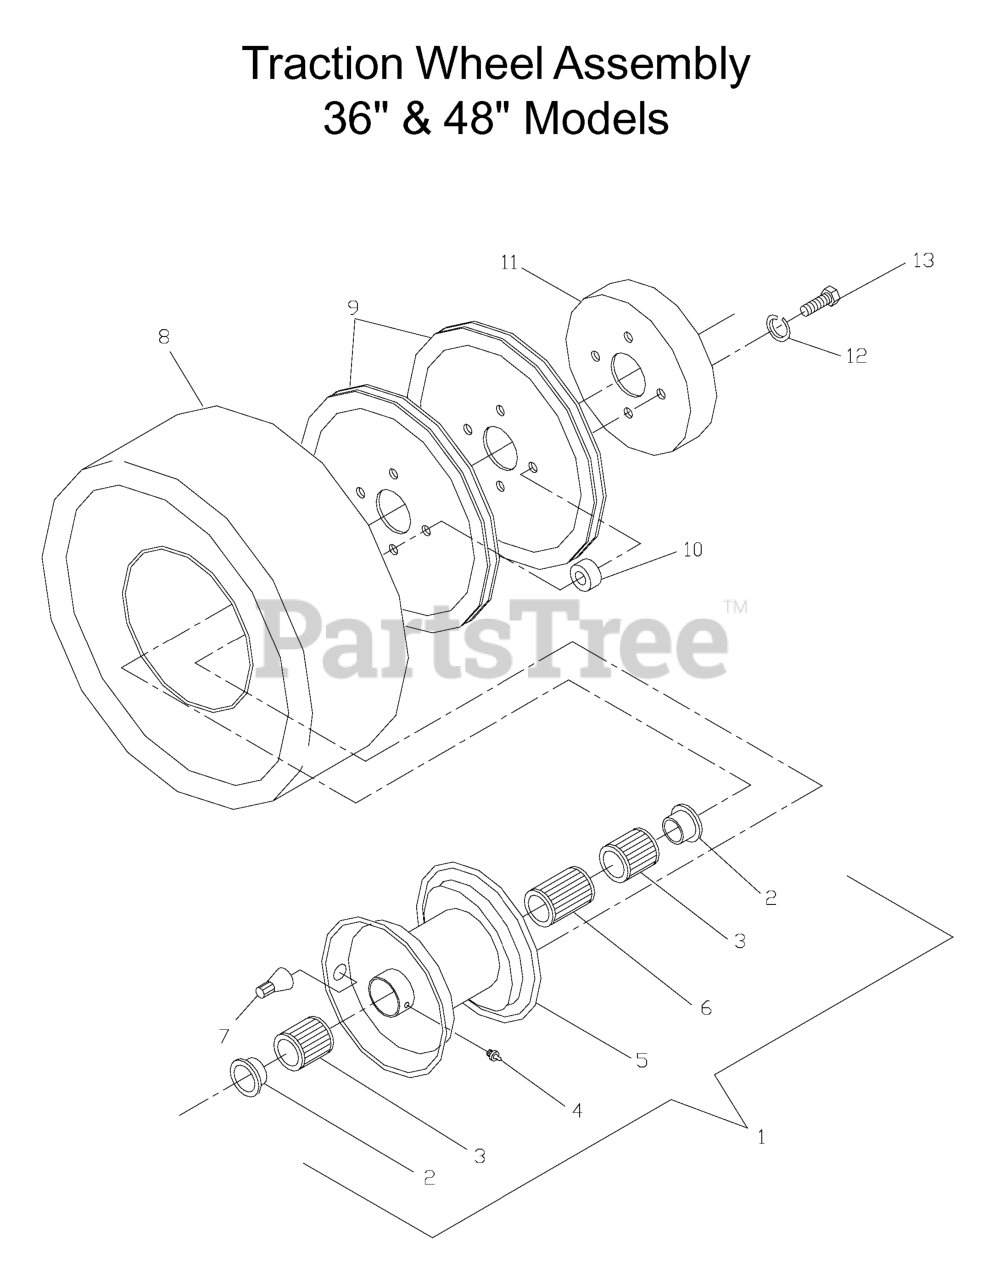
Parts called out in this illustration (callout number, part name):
1	WHEEL.ASM.13X6.5-6.SILVER.COMM
2	BEARING FLANGE
3	ROLLER BEARING (SHORT)
4	ZERK
5	RIM
6	ROLLER BEARING (LONG)
7	VALVE STEM TR-412
8	TIRE
9	TRACTION PULLEY
11	BRAKE DRUM
12	SLW 3/8 STD
13	HCS 3/8F X 1 1/2
